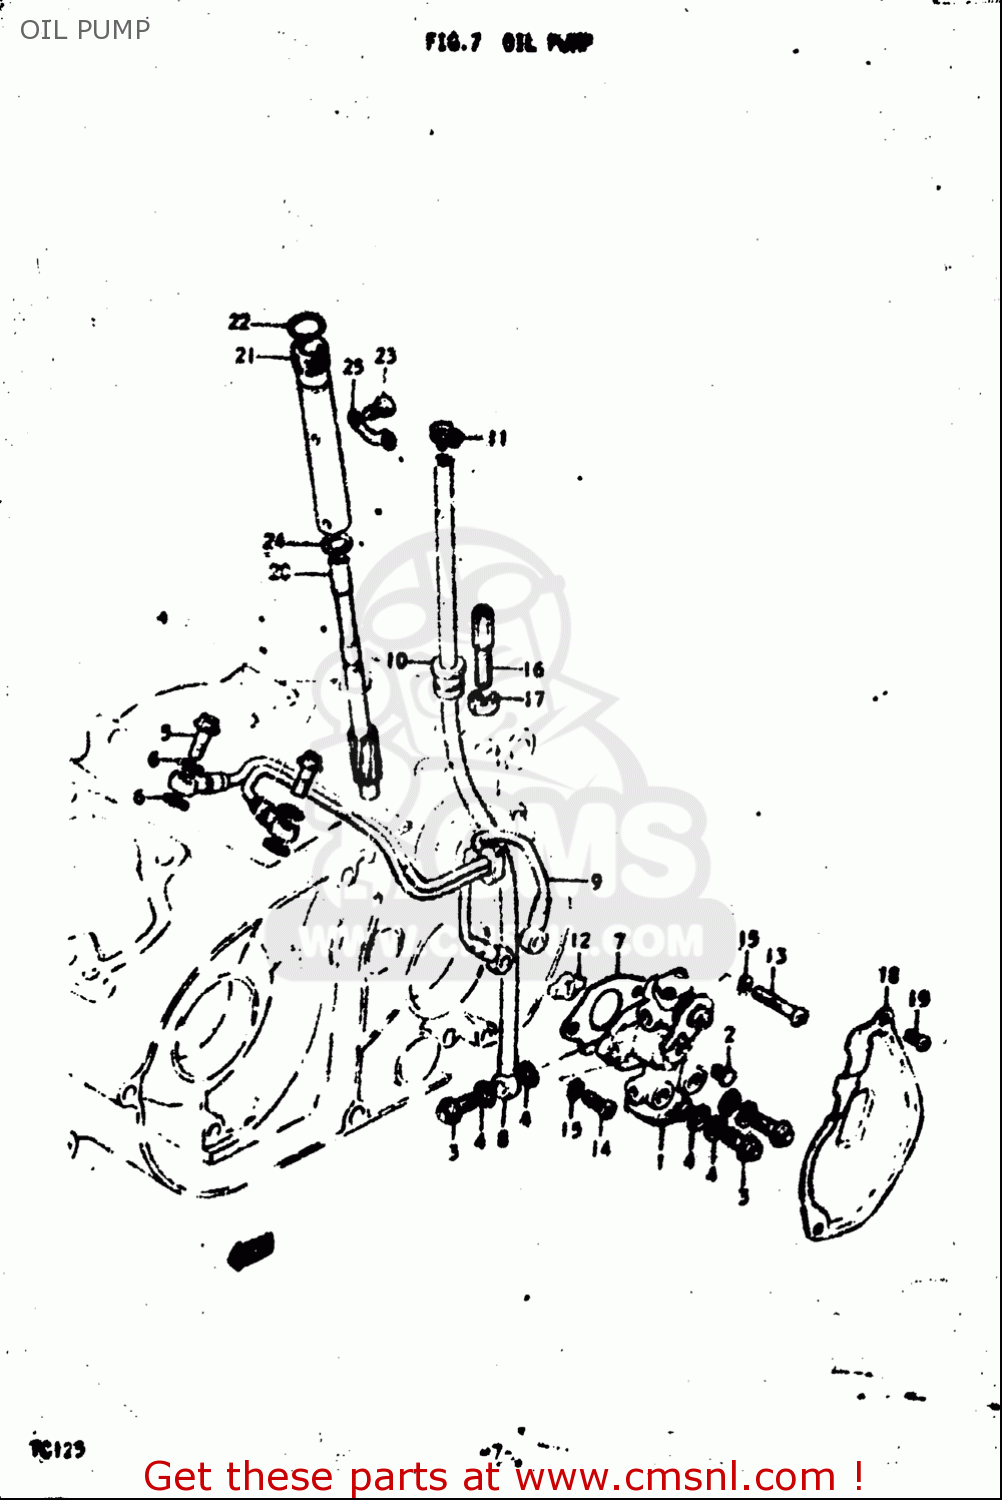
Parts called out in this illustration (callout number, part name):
2	TERMINAL,CABLE
3	UNION BOLT
4	GASKET(6.2X11X1).2 (NAS)
5	UNION BOLT
6	GASKET(8.2X14X1) (NAS)
7	GASKET,OIL PUMP (NAS)
8	HOSE,INLET
11	CLAMP
12	PIECE,OIL PUMP DRIVE
13	SCREW
14	SCREW
15	WASHER,LOCK
16	BOLT
17	NUT
18	CAP,OIL PUMP INSPECTION
19	SCREW
21	SLEEVE,TACHOMETER DRIVEN GEAR
22	O RING(D:1.3,ID:9.6)
24	NUT
